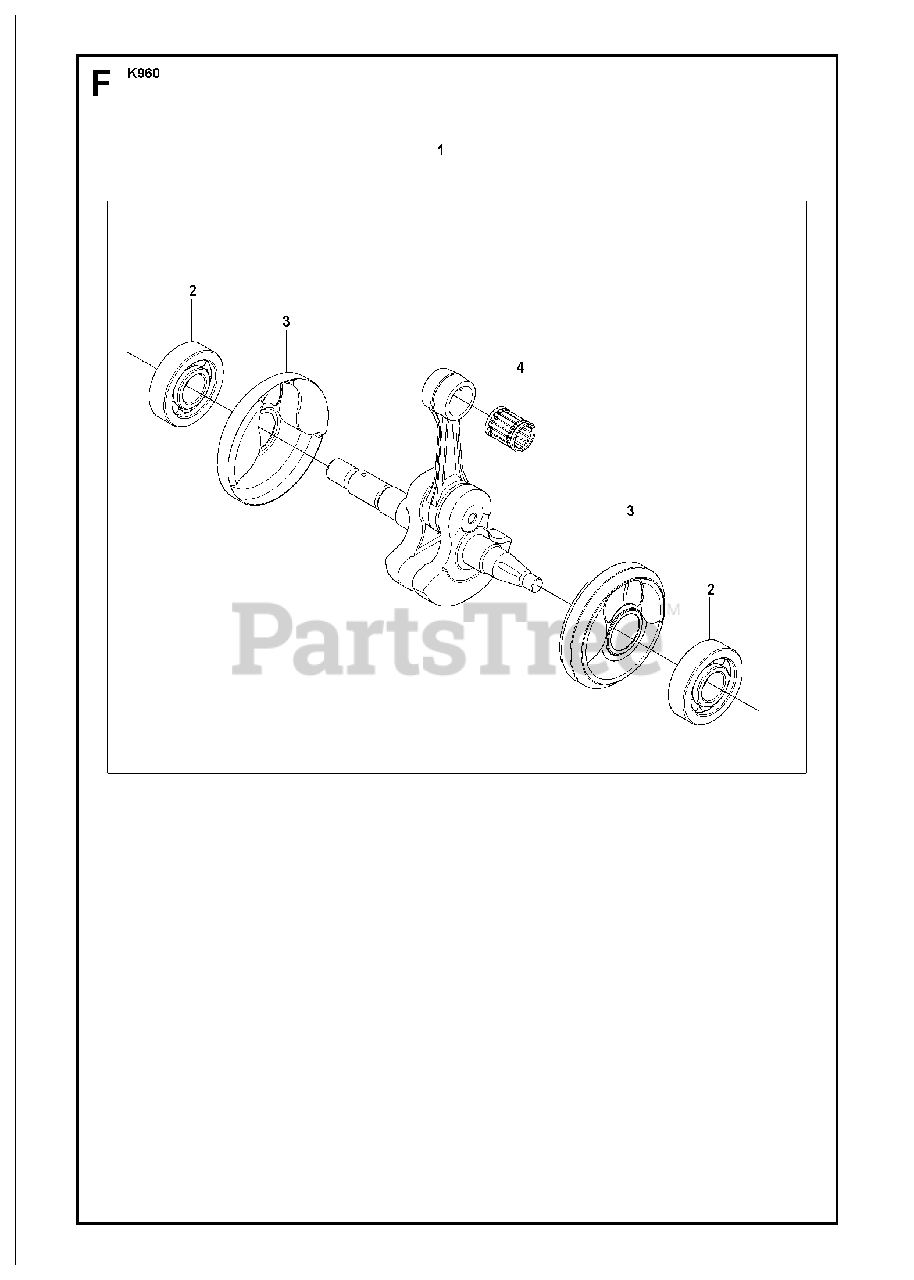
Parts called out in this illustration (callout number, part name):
1	CRANKSHAFT ASSYIncl. 2 - 4
2	BALL BEARING
4	NEEDLE BEARING
